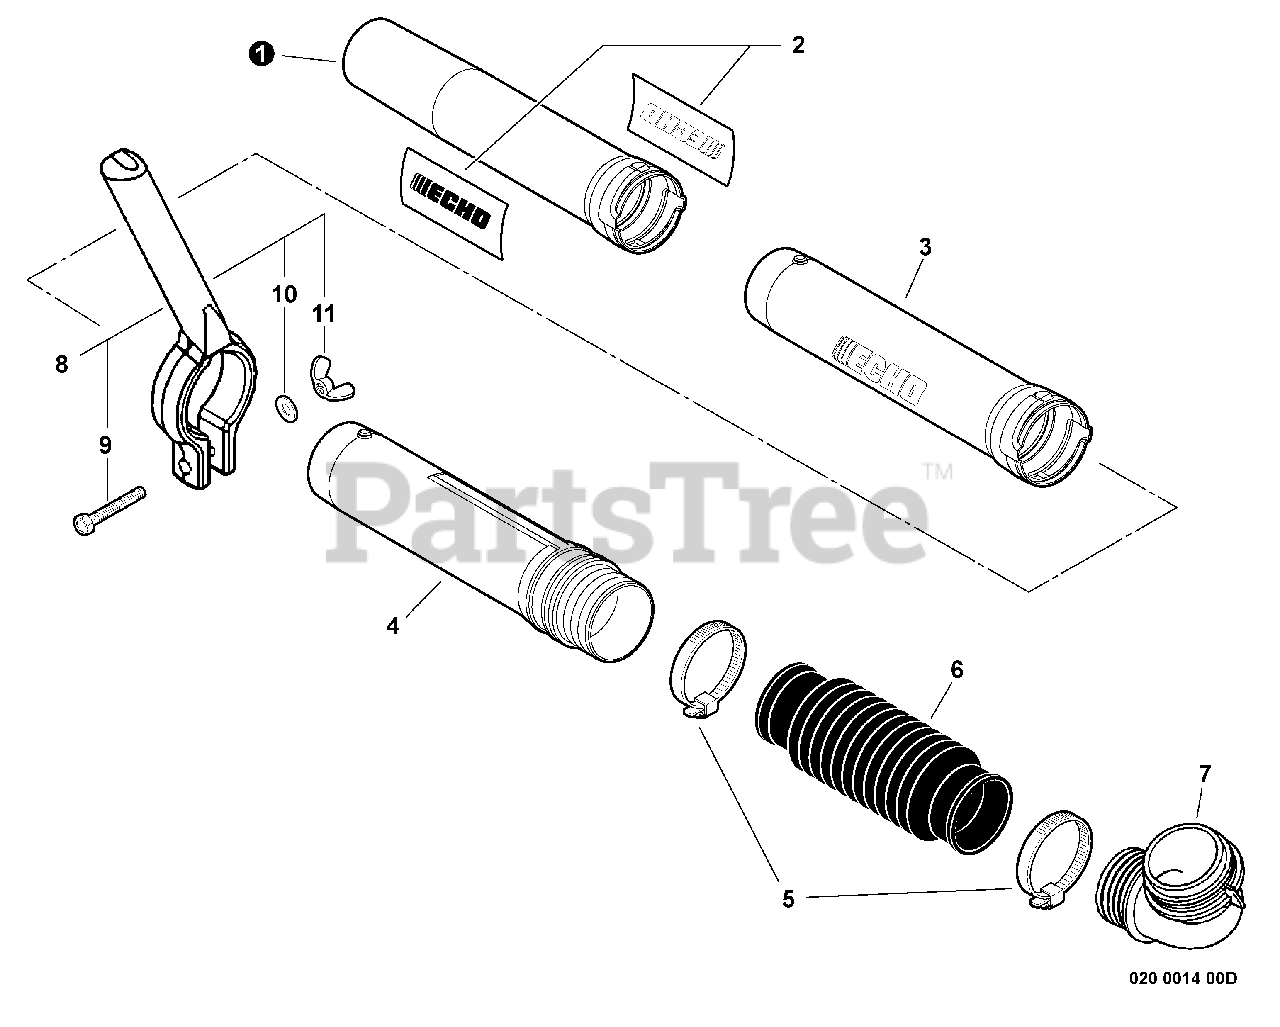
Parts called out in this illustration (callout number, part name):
1	TUBE, BLOWER - STRAIGHT
2	LABEL - ECHO
3	TUBE, BLOWER - STRAIGHT
4	TUBE, BLOWER - SWIVEL
5	CLAMP, HOSE
6	TUBE, BLOWER - FLEXIBLE
7	TUBE, BLOWER - ELBOW
8	TUBE MOUNT HANDLE
9	BOLT - 6X45
10	WASHER - 6
11	WINGNUT - 6
